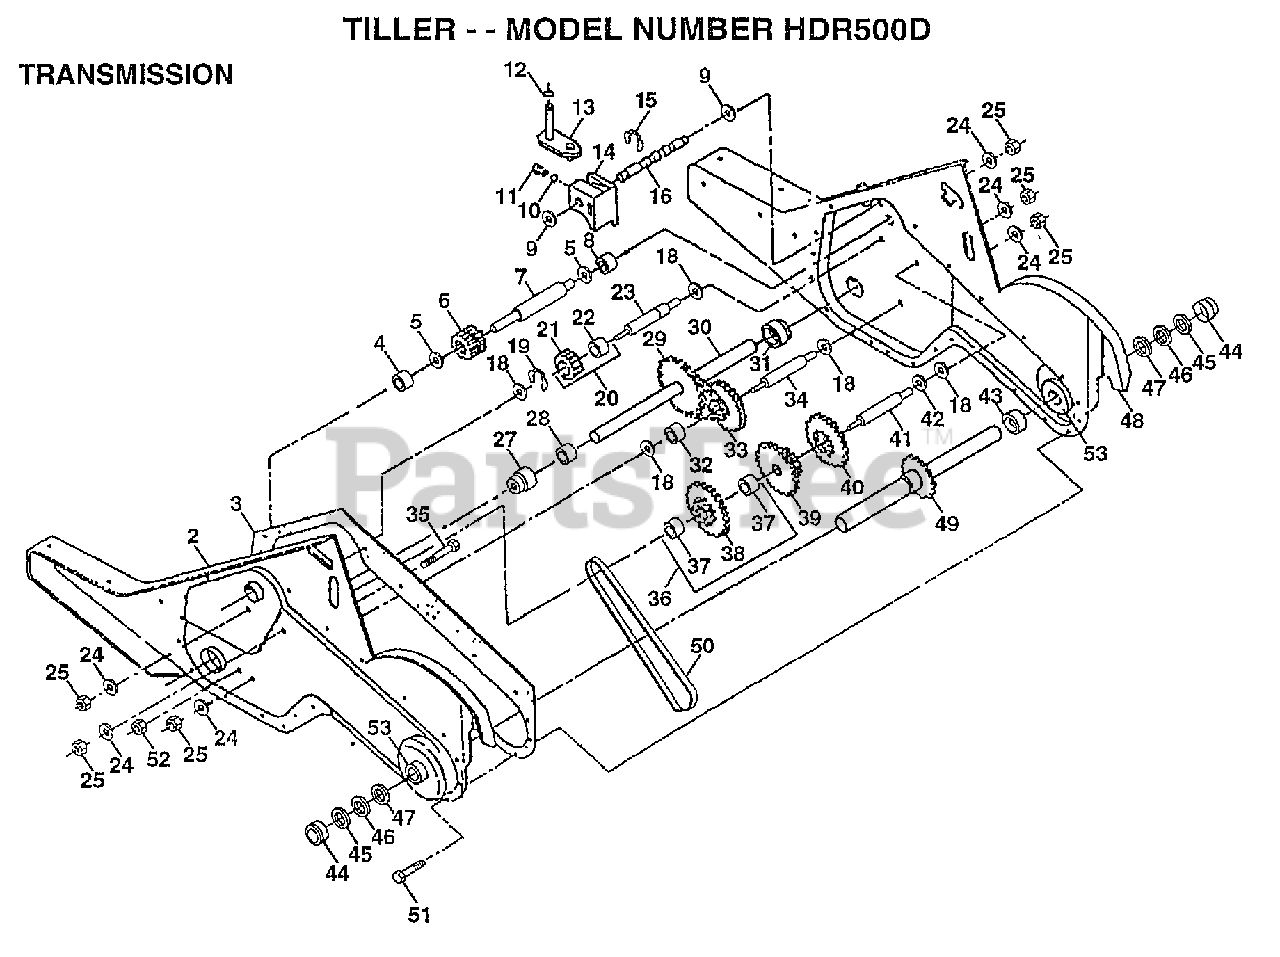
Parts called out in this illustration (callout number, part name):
2	GEARCASE LH W/BRG
3	GASKET TI
4	NEEDLE BRNG LT
5	"T, BEARING"
6	GEAR PINION INPUT
7	"SHAFT.INPUT.""D"""
8	"TI, BEARING"
9	WASHER SEAL
11	SPRING-SHIFT CRT
12	O-RING TI
13	BRACKET ASM SHIFT
14	SHIFT FORK TI
15	KLIP RING
16	SHAFT.SHIFTER
18	WASHER
19	KLIP RING
20	GEAR ASSY CRT
22	NEEDLE BEARING TI
23	SHAFT CRT
24	LOCKWASHER
25	NUT.ASF.HEX.7/16
27	BEARING.SHAFT.LH.
28	BUSHING TI
29	CHAIN CRT
30	GROUND SHAFT ASSY
31	BEARING.SHAFT.RH.
32	SPACER TI
33	SPRCKT 8 GEAR CRT
34	SHFT 2ND RED. CRT
35	SCRW WHIZ LOK CRT
36	SPROCKET.ASM.W/BR
37	BEARING
39	GEAR TI
40	GEAR TI
41	REDUCTION SHFT TI
42	BRNG RACE
43	SPACER TI
44	CUP.FORMED.
45	RING SPIRAL CRT
46	SEAL RING RUBBER
47	OIL SEAL STD
48	GEARCASE RH W/BRG
49	TINE SHAFT
50	CHAIN.50 LINK TI
51	SCREW
52	NUT.HEX.5/16-18
